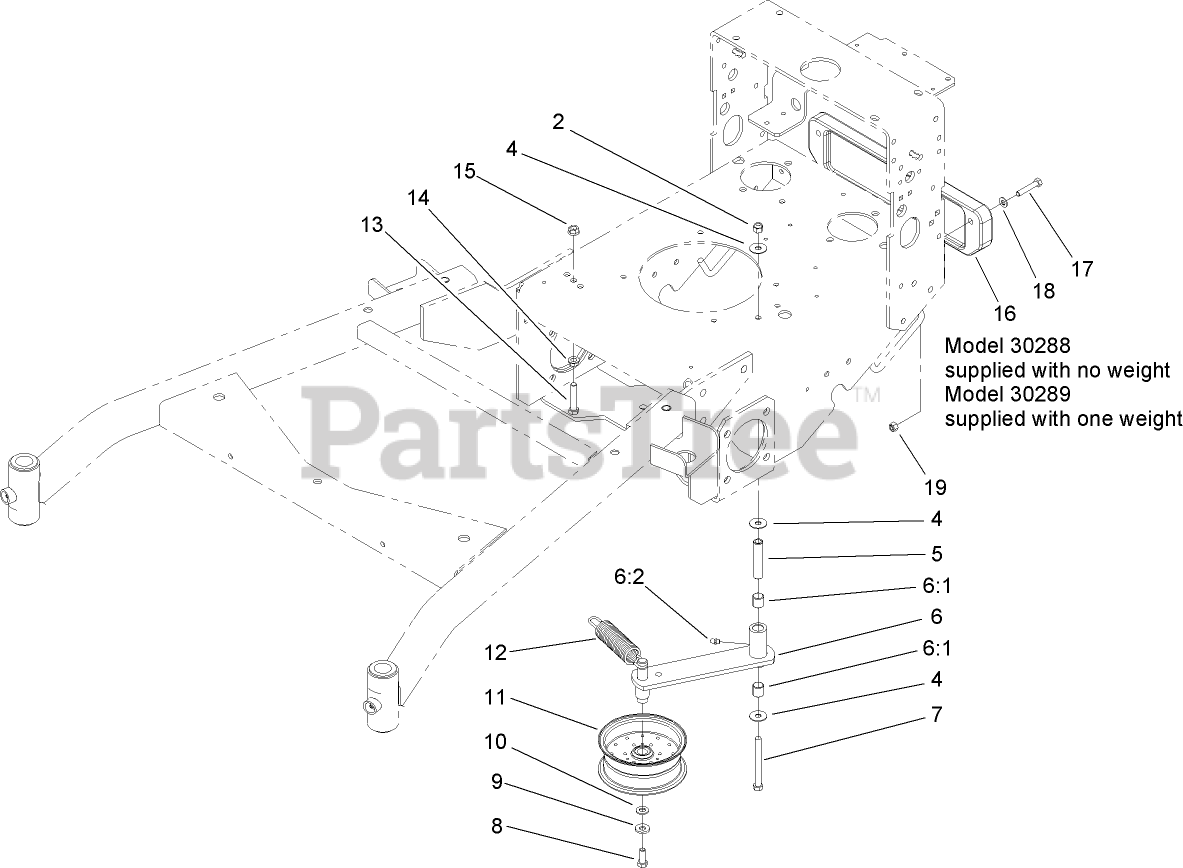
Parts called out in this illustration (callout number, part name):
2	NUT-LOCK, NI
4	WASHER
5	TUBE-IDLER
6	IDLER ARM ASM
6:1	SLEEVE-BEARING
6:2	FITTING-GREASE
7	SCREW-HH
8	SCREW-HH
9	WASHER-BELLEVILLE
10	WASHER-FLAT
11	PULLEY-IDLER
12	SPRING-EXTENSION
13	SCREW-HH
14	NUT-HHF, WHIZ
15	NUT-HF
16	WEIGHT-CAST
17	SCREW-HH
18	WASHER-PLAIN
19	NUT-LOCK, NI
